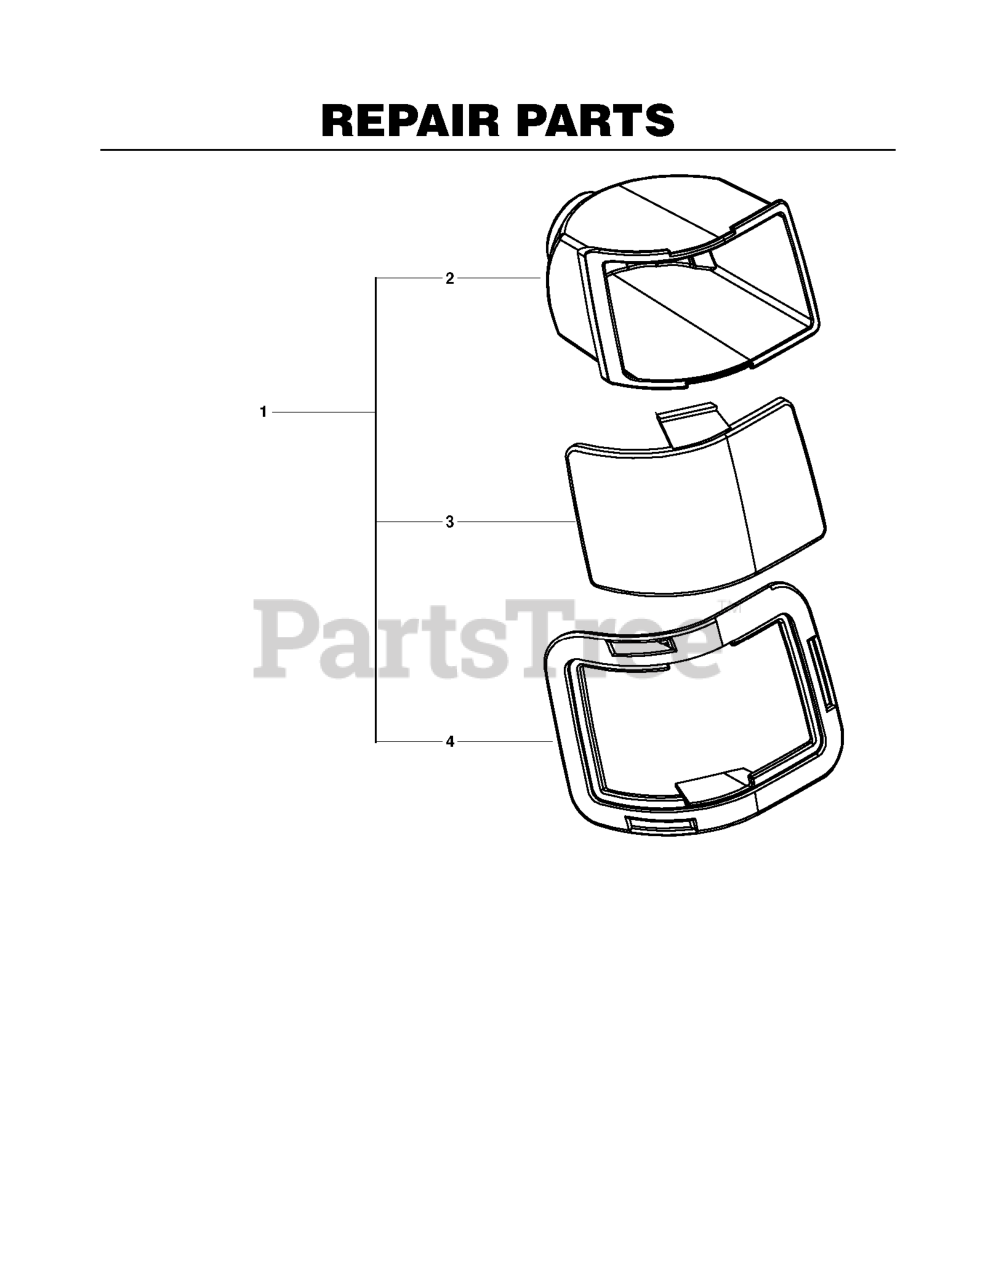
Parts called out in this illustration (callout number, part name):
1	HEADLIGHT ASM, RT
2	REFLECTOR, HEADLIGHT RT
3	RT HEADLIGHT LENS
4	RT HEADLIGHT RIM GREY
